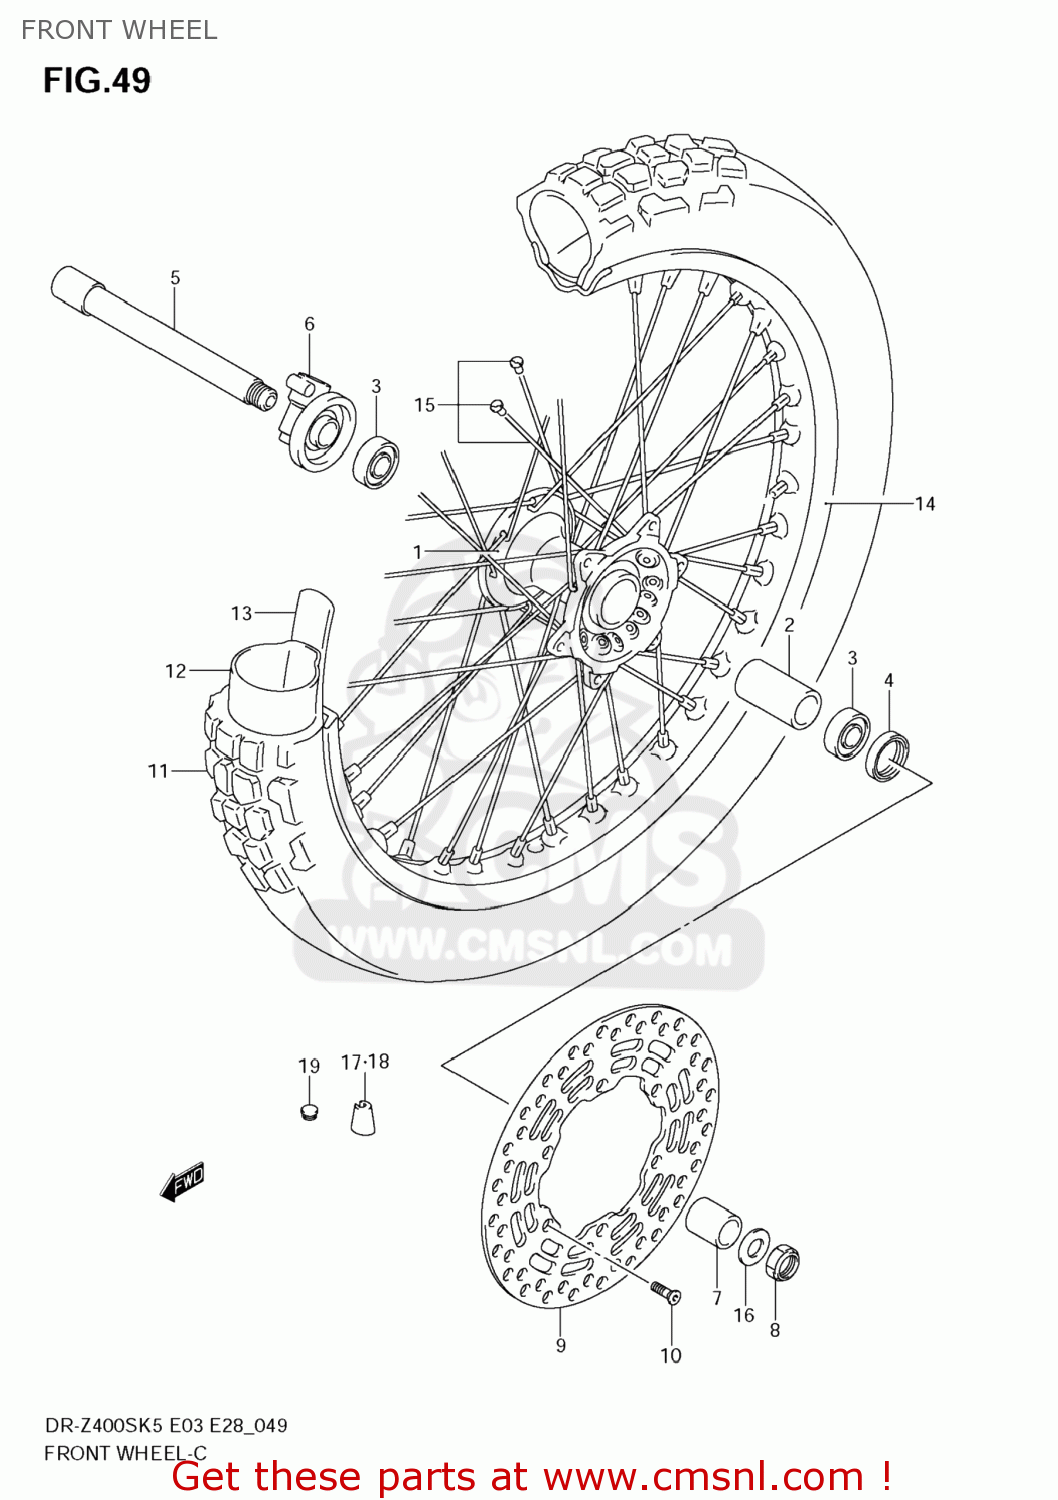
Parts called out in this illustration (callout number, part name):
1	HUB,FR WHEEL
2	SPACER,FR HUB BEARING
3	BEARING
4	SEAL,OIL(25X37X6)
5	AXLE,FR
6	BOX ASSY,SPEEDOMETER GEAR
7	SPACER,FR AXLE,L
8	NUT
9	DISC,FR BRAKE,L
10	SCREW(6X18)
11	TIRE,FR(80/100-21 51P)
12	TUBE ASSEMBLY,WHEEL,INNER
13	PROTECTOR,WHEEL,INNER
14	RIM,FR WHEEL(21X1.60 AL)
15	SPOKE SET,FR WHEEL
16	WASHER(18X26X2.8)
17	BALANCER,WHEEL(20G)
18	BALANCER,WHEEL(30G)
19	CAP(OD:12)
